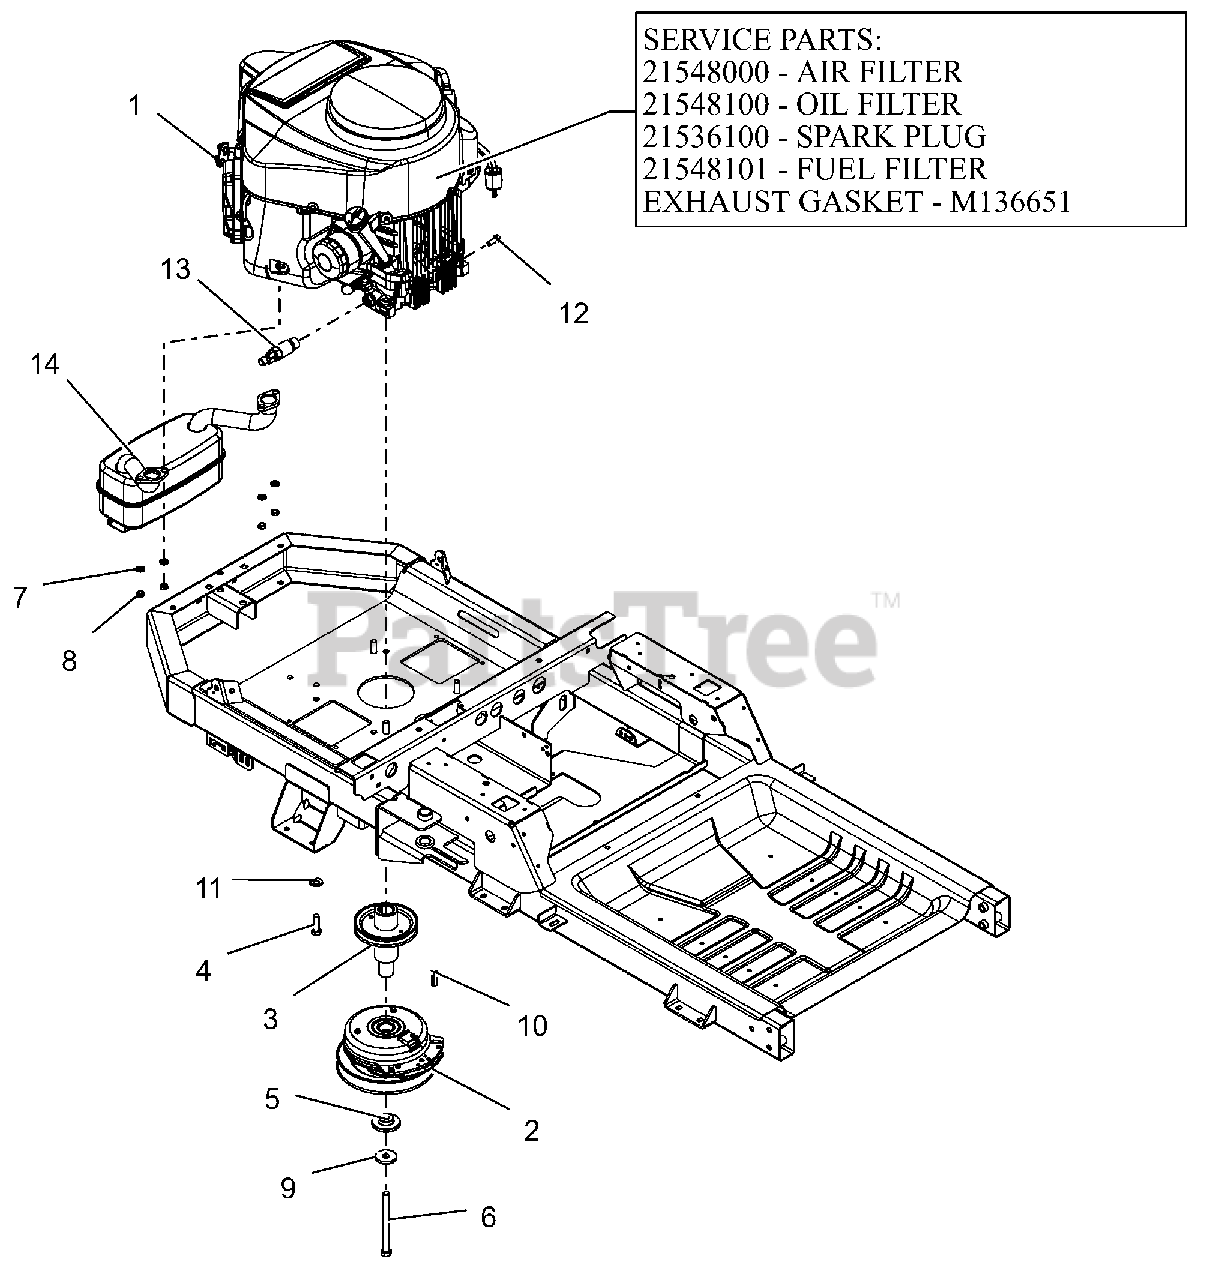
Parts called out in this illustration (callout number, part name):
1	ENGINE, KAWASAKI FR730 24HP
1	AIR FILTER, KAWASAKI FR
1	OIL FILTER, KAWASAKI FR
1	PLUG, SPARK
1	FUEL FILTER-KAWASAKI FR
1	GASKET, MUFFLER #
2	CLUTCH,105FTLB MONOPOLE 6.83"
3	WLDMT, DRIVE SHEAVE (LG XL)CZC
4	BLT, HEX .38-16X1.25 G5 ZCC NT
5	BSHG-FLG .469X1.06X.574X2.0
6	BLT-HEX.438-20X5 GR8 YZ NYTORQ
7	WSHR,LK-REG .312X.078 ZCC
8	NUT,NYL M8-1.25 G8.8 ZCC
9	WASHER, 7/16" SPRING DISK
10	KEY-SQ .25 X 1.25 X .25 SAE
11	WASHER, 3/8" SPRING DISC
12	BLT, HEX M8-1.25X20 G8.8 ZCC
13	DRAIN, OIL M20X2.5
14	MUFFLER - KAWASAKI
